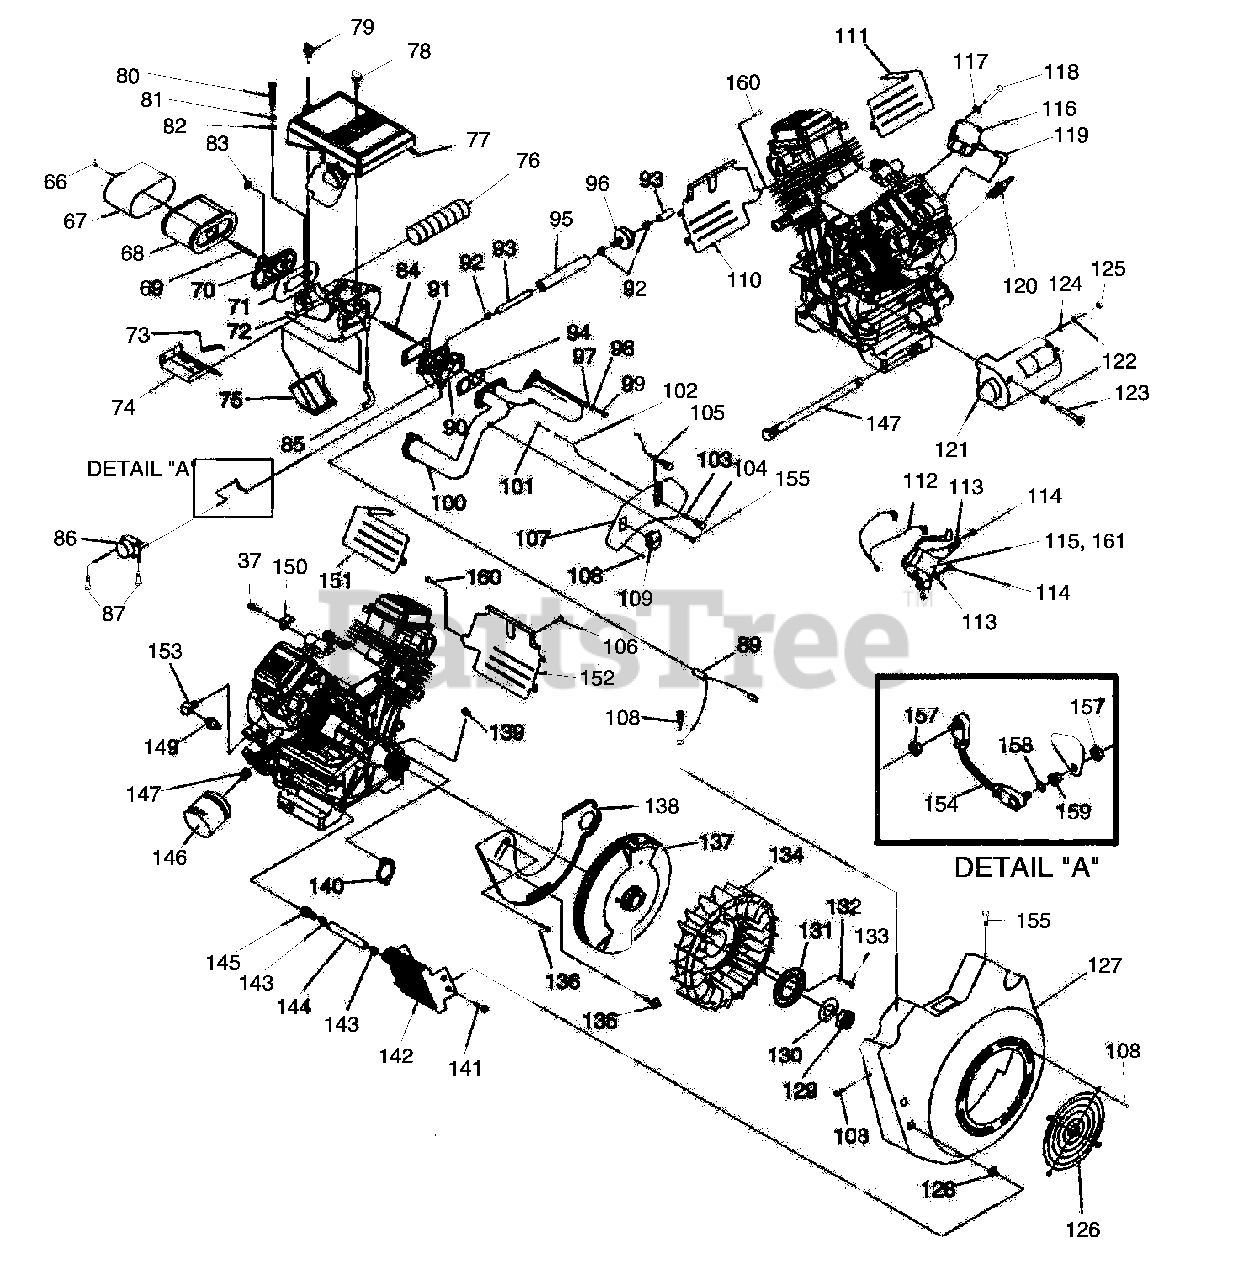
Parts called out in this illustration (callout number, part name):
66	WINGNUT, AIRBOX
67	PRECLEANER, AIR
68	ELEMENT, AIR CLEANER
69	STUD M6-1.0 X 73
70	ADAPTER, SPIT BACK
71	GASKET, SPITBACK
72	BASE, AIRBOX (GT-990)
73	SPRING, WINTER/SUMMER VALVE
74	VALVE, SUMMER/WINTER
75	SNORKEL, AIR INTAKE
76	TUBE, HEAT RISER 50.8 I.D.
77	COVER, AIRBOX
78	KNOB, AIRBOX 17mm
79	KNOB, AIRBOX 95MM
80	SCREW HHC M6-1.0 X 35
81	WASHER LOCK M6-1/4
82	WASHER FLAT 1/4
83	NUT LOCK FLANGE M6-1.0
84	STUD, METRIC
85	HOSE, BREATHER
86	CONTROLLER ASSEMBLY
87	SCREW HHTT M5-0.8 X 10
89	ASSEMBLY, WIRE
90	CARBURETOR (GT-990)
91	GASKET, CARB TO SPACER (GT-990)
92	CLAMP HOSE BAND 1/4
93	HOSE1/4 ID
94	GASKET, MANIFOLD TO CARB (GT-990)
95	SLEEVING 1/2" I.D
96	FILTER, FUEL
97	WASHER FLAT M8
98	WASHER LOCK M8
99	SCREW SHC M8-1.25 X 30
100	MANIFOLD, INTAKE
101	NUT HEX M3-0.5
102	ROD, SUMMER / WINTER VALVE
103	BUSHING, MINI CONTROL PANEL
104	KNOB, CONTROL SUMMER / WINTER
105	CHOKE ASSEMBLY
106	SCREW TAPTITE M5-0.8 X 8 ZP
107	PANEL, CONTROL FACE PLATE
108	SCREW TAPTITE M6-1.0X 10 YELLOW CHROME
109	SWITCH ROCKER
110	WRAPPER, LOWER CYLINDER 2
111	WRAPPER, UPPER CYLINDER 2
112	ASSEMBLY, GROUND WIRE
113	WASHER LOCK M6-1/4
114	SCREW TAPTITE M6-1.0 X 25 BP
115	ASSEMBLY, IGNITION COIL
116	PUMP, IMPULSE
117	WASHER LOCK M4
118	SCREW PPHM M4-0.7 X 40
119	ELBOW, RUBBER 90 DEG.
120	SPARKPLUG, CHAMPION RC14YC
121	STARTER, DELCO REMY SD80
122	WASHER LOCK M8-5/16
123	SCREW HHC M8-1.25 X 85 G8.8
124	WASHER, FLAT M8
125	NUT, HEX M8-1.25 G8
126	GUARD, FAN
127	HOUSING, BLOWER GASOLINE COOLER
128	NUT, GROMMET 1/4 PLUG
129	NUT,HEX M24
130	WASHER, M24
131	PLATE, FAN
132	WASHER SHAKEPROOF INT M8 SS
133	SCREW HHC M8-1.25 X 12 G8.8
134	FAN, NYLON
135	INSULATOR ASSEMBLY IGNITION
136	SCREW TAPTITE M6-1X10 YELLOW CHROME
137	FLYWHEEL ASSEMBLY
138	PLATE, BACKING GT990 WITH OIL COOL
139	KEY, WOODRUFF 4 X 19D
140	GASKET, MANIFOLD / PORT
141	PLASTITE,1/4-15 X 3/4
142	COOLER, OIL
143	CLAMP HOSE .38-.87
144	HOSE, 3/8" I.D. X 6" LONG
145	BARBED STR 1/4NPT X 3/8 WITH VIBRA SEAL
146	FILTER, OIL D 69 X 64 LONG
147	NIPPLE, 3/4"-16 UNF
148	ASSEMBLY, OIL DRAIN HOSE
149	SWITCH, OIL PRESS
150	BRACKET, AIRBOX SUPPORT
151	WRAPPER, UPPER CYLINDER 1
152	WRAPPER, LOWER CYLINDER 1
153	BRASS ST ELBOW 1/4 NPT
154	ASSY, ROD, GOV. STEPPER MOTOR
155	SCREW HHHC M6-1.0 X12
157	NUT, LOCK HEX M3-0.5 (GT-990)
158	WASHER FLAT #4 (GT-990)
159	SPACER, ROD (GT-760 ONLY)
